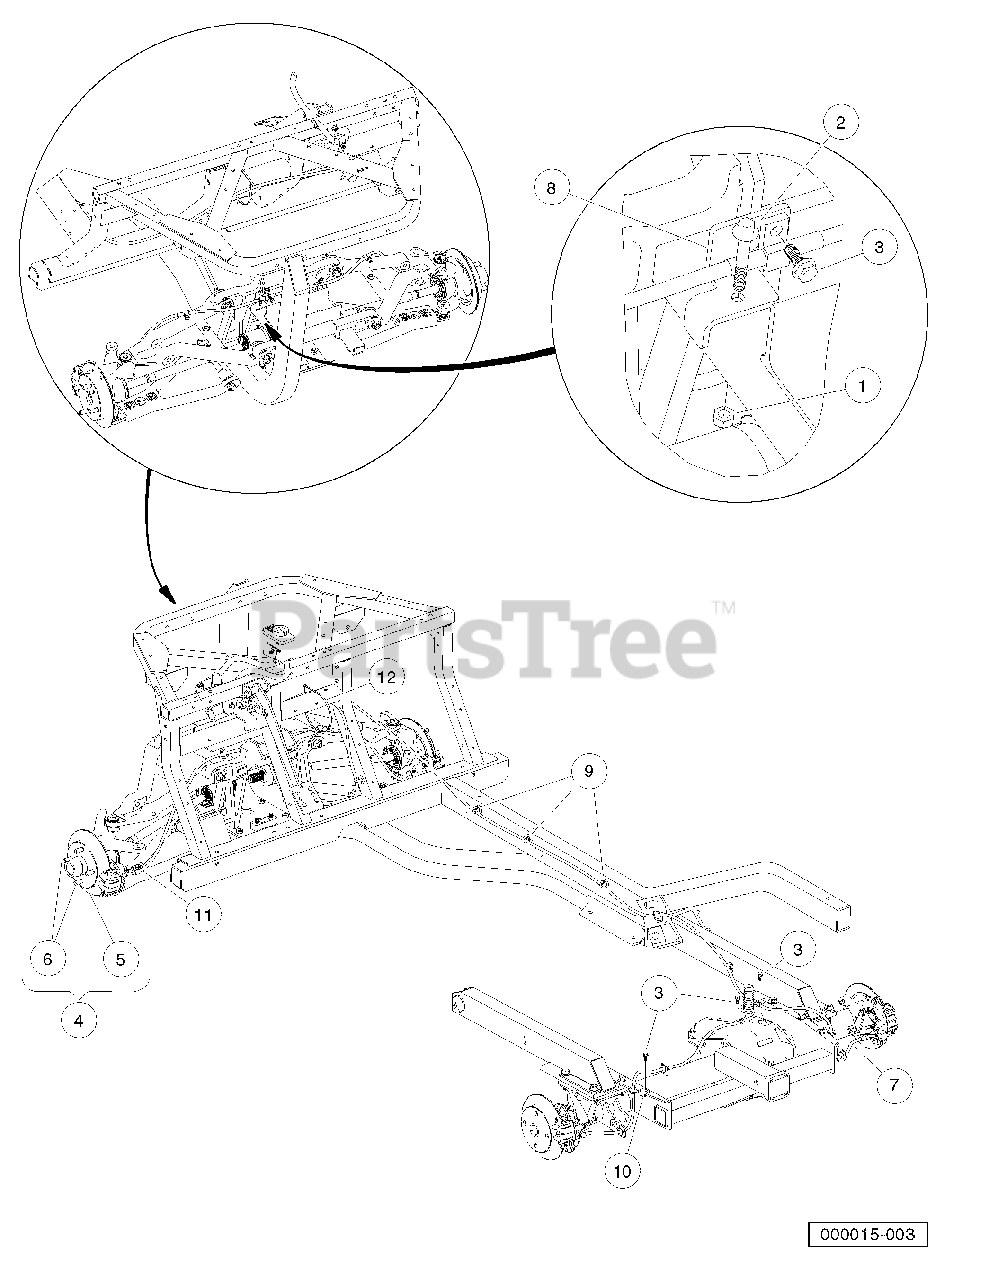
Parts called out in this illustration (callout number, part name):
1	Locknut, M6-1.00 Nylon Insert
2	Bolt, Flanged Head, M6x1.0x40
3	Screw, M6 X 16 Tt Hx Fl Hd
4	Assy, Rotor, Brake, Front, Wt
5	Rotor, Brake, Front, Wt
6	Stud, Wheel Lug
7	Assembly, Brake Line, Rear
8	Bracket, Tee, Brakeline
9	Clip, Brake Line
10	Bracket, Line, Hydraulic
11	Brakeline, Front, Assembly
12	Tie Wrap, 11" Nylon
